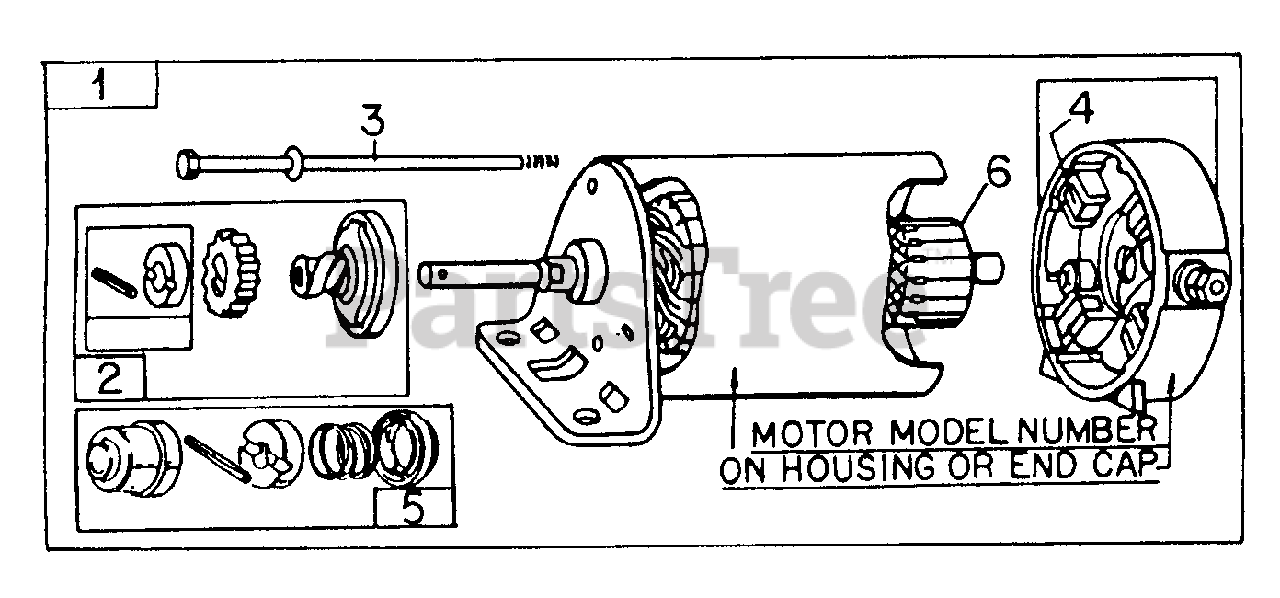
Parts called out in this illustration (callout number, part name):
1	Motor Assy, Starter
2	Drive Assy
3	Bolt, Thru
5	Kit, Pinion Spring
6	Armature Assy
